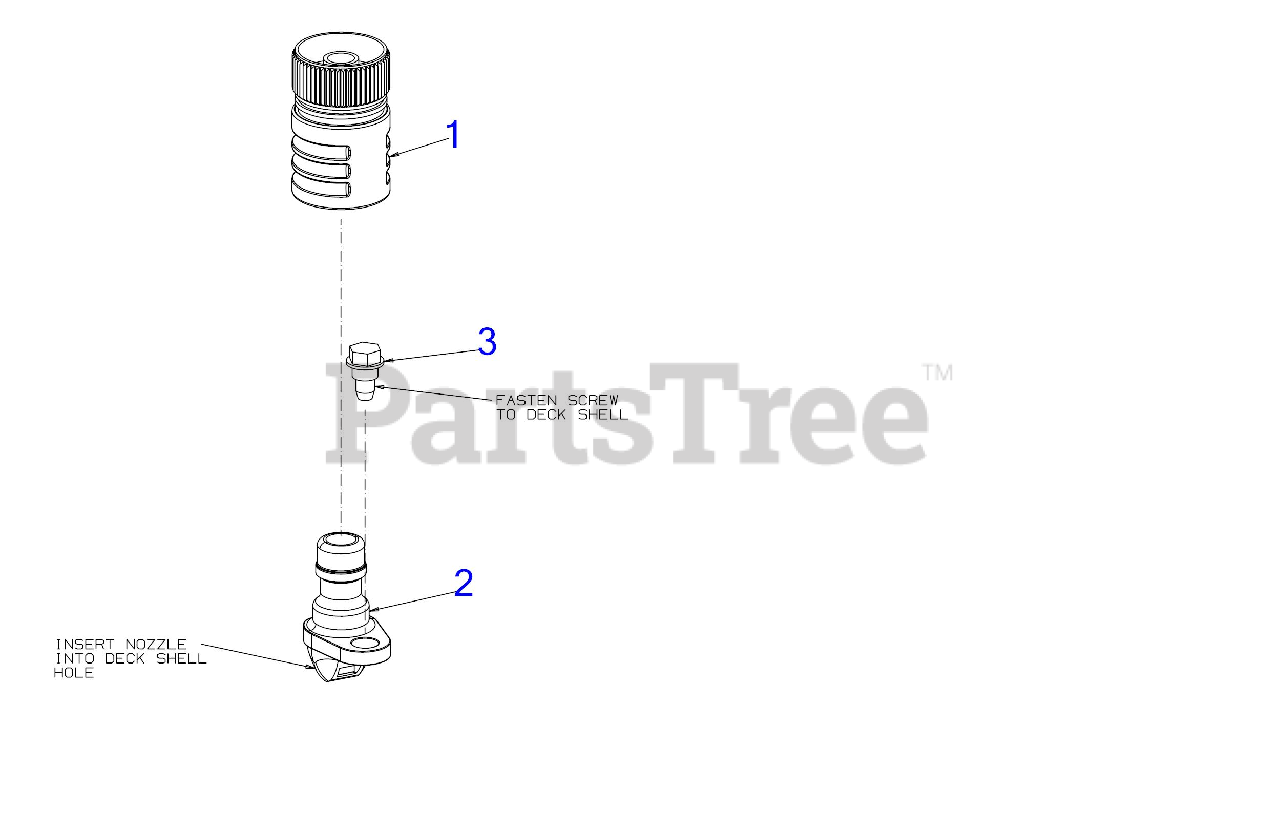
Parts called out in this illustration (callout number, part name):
1	WATER NOZZLE ADAPTER
2	DECK WASH NOZZLE
3	SHOULDER SCREW 1/4-20 x .50
